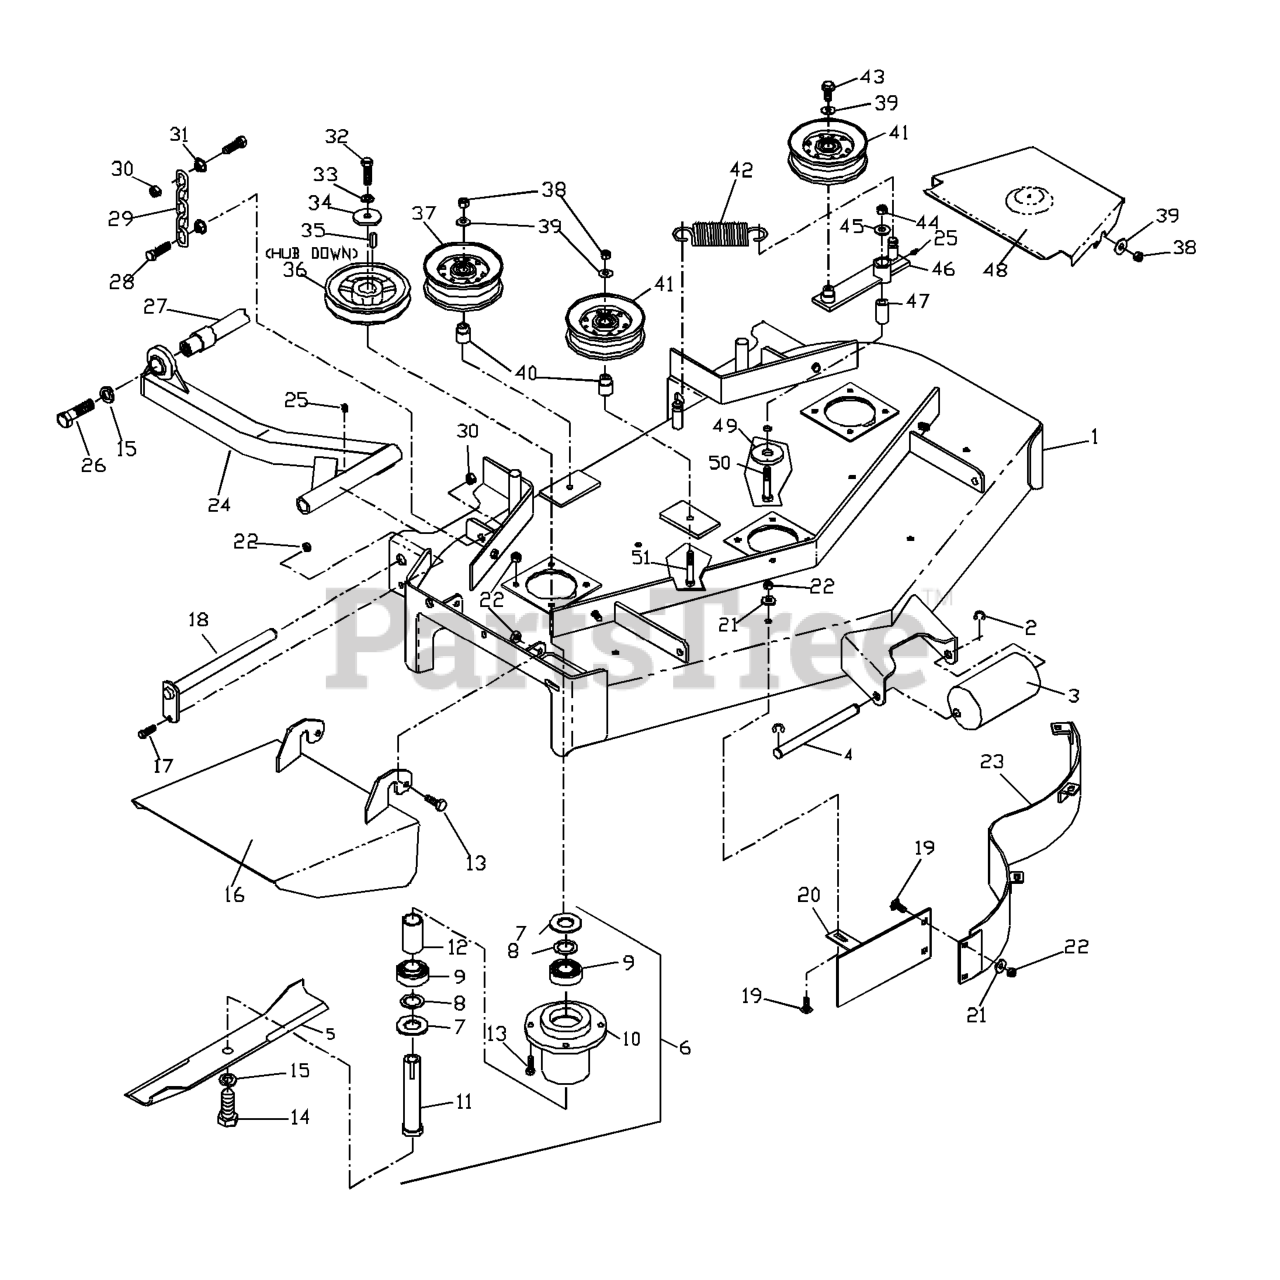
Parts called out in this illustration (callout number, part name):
1	DECK W/DECALS HUS
2	E-RING 1/2 (2 2)
5	BLADE OEM, 14-7/8
6	HOUSING, COMPLETE
7	MACHINERY BUSHING 10 GA.
8	BUSHING.MACHINE.18.GAUGE
9	BEARING
11	SPINDLE SHAFT
13	HCS 5/16C X 1
14	HCS 5/8F X 1 1/4
15	LOCKWASHER 5/8
16	DISCHARGE CHUTE 42"
17	HCS 5/16C X 3/4
19	CARRIAGE BOLT 5/16C X 5/8"
20	CENTER BAFFLE
21	WASHER 5/16 FLAT
22	NUT 5/16C CENTERLOCK
23	MAIN BAFFLE
24	STRUT WLDMT - RT
24	STRUT SLDMT-LT
25	ZERK
26	HCS 5/8C X 2 GR.5
27	STRUT MOUNT WELDMENT
28	HCS 7/16C X 1 1/2
29	LIFT CHAIN
30	NUT 7/16C CENTERLOCK
31	NUT 7/16C WHIZ
32	HCS 7/16F X 1 1/2
33	WASHER 7/16 LOCK
34	SPINDLE WASHER
35	KEY 1/4 SQ X 1 1/8
37	IDLER PULLEY (TALL)
38	NUT 3/8C CENTERBLOCK
39	WASHER 3/8 FLAT
40	IDLER BUSHING
41	IDLER PULLEY
43	4CS 3/8C X 1 SERRATED HEAD
44	NUT 1/2-13 HEX NYLOC ZD
45	WASHER 1/2 FLAT
47	PIVOT BUSHING
48	BELT SHIELD
49	WASHER, SUPPORT
50	HCS 1/2C X 3 1/4
51	HCS 3/8C X 2 1/2
52	BELT, DECK 42"
53	DECAL, NO STEP
54	DECAL, CPSC
55	DECAL, DANGER
